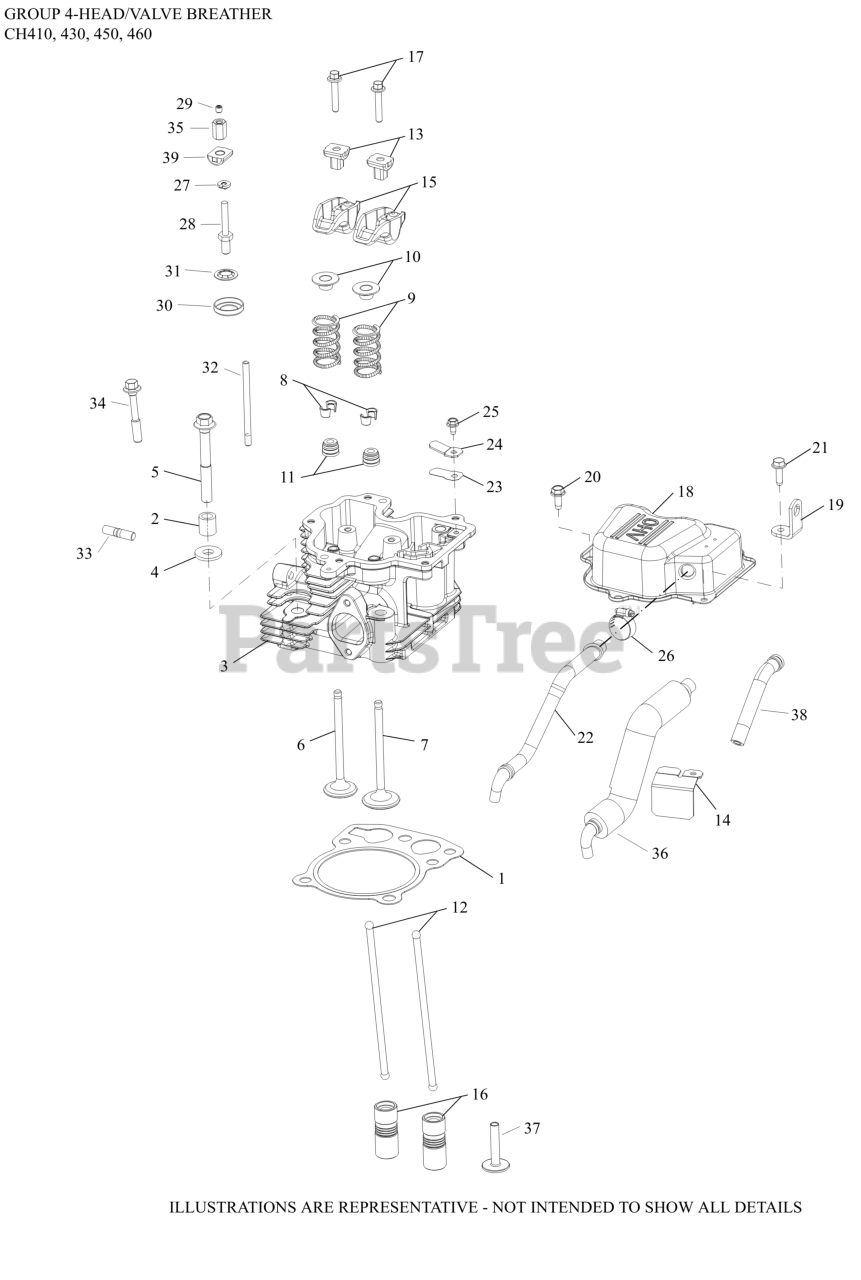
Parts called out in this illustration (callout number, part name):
1	GASKET, CYLINDER HEAD
2	SPACER, HEAD BOLT EXHAUST PORT
3	HEAD ASSEMBLY, CYLINDER
4	WASHER, FLAT 13/32"
5	SCREW, CYLINDER HEAD (M10 X 80)
6	VALVE, EXHAUST
6	VALVE, EXHAUST (.25 MM)
7	VALVE, INTAKE
7	VALVE, INTAKE (.25 MM)
8	KIT, RETAINER
9	SPRING, VALVE
10	CAP, VALVE SPRING
11	SEAL, VALVE STEM-USE 25 032 14-S
12	ROD, PUSH
13	PIVOT, ROCKER ARM
15	ARM, ROCKER
16	LIFTER, VALVE HYDRAULIC-USE 25 351 11-S
17	SCREW, FLG (BLACK) M6X1.0X34
18	COVER, ROCKER
19	STRAP, LIFTING
20	SCREW,FLG THD FRM M6X1.0X16-(#25086397S)
21	SCREW,FLG THD FRM M6X1.0X20-(#25086396S)
22	HOSE, BREATHER
23	REED, BREATHER
24	RETAINER, REED
25	SCREW, FLG THD FRM M5X.8X10
